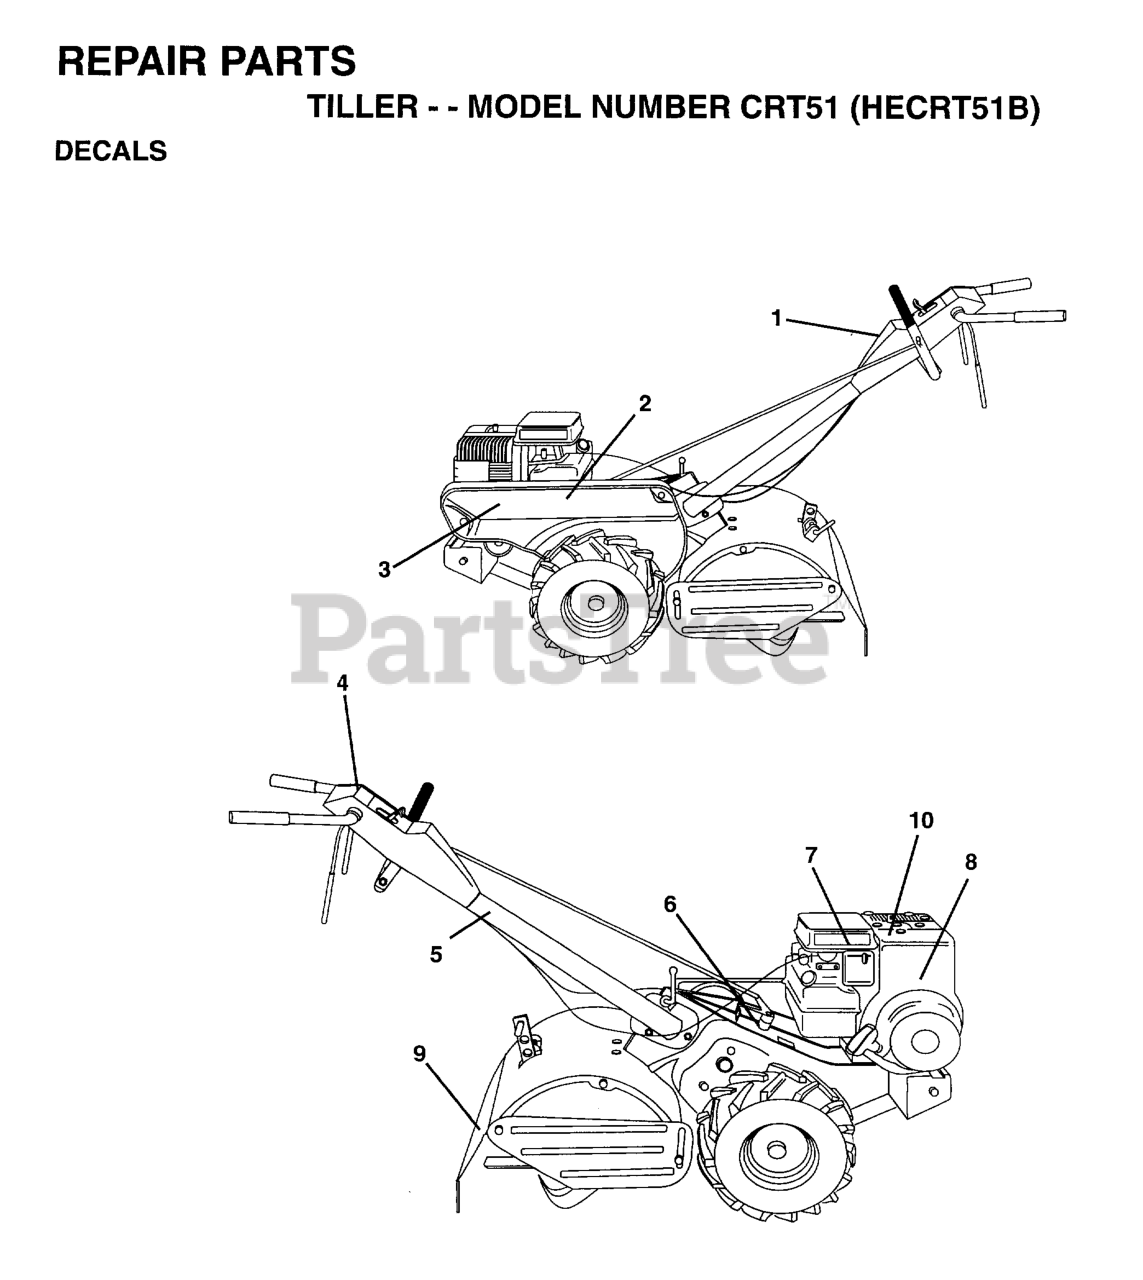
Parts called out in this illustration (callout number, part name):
1	DECAL, LOGO
2	NAMEPLATE HUSQVARNA
4	DECAL INST CONTROL PANEL
5	DECAL TI (2 2)
6	DECAL TI NLA
8	DECAL, B & S ENGINE
9	DECAL TI
10	DECAL EUROPE STANDARD CE
